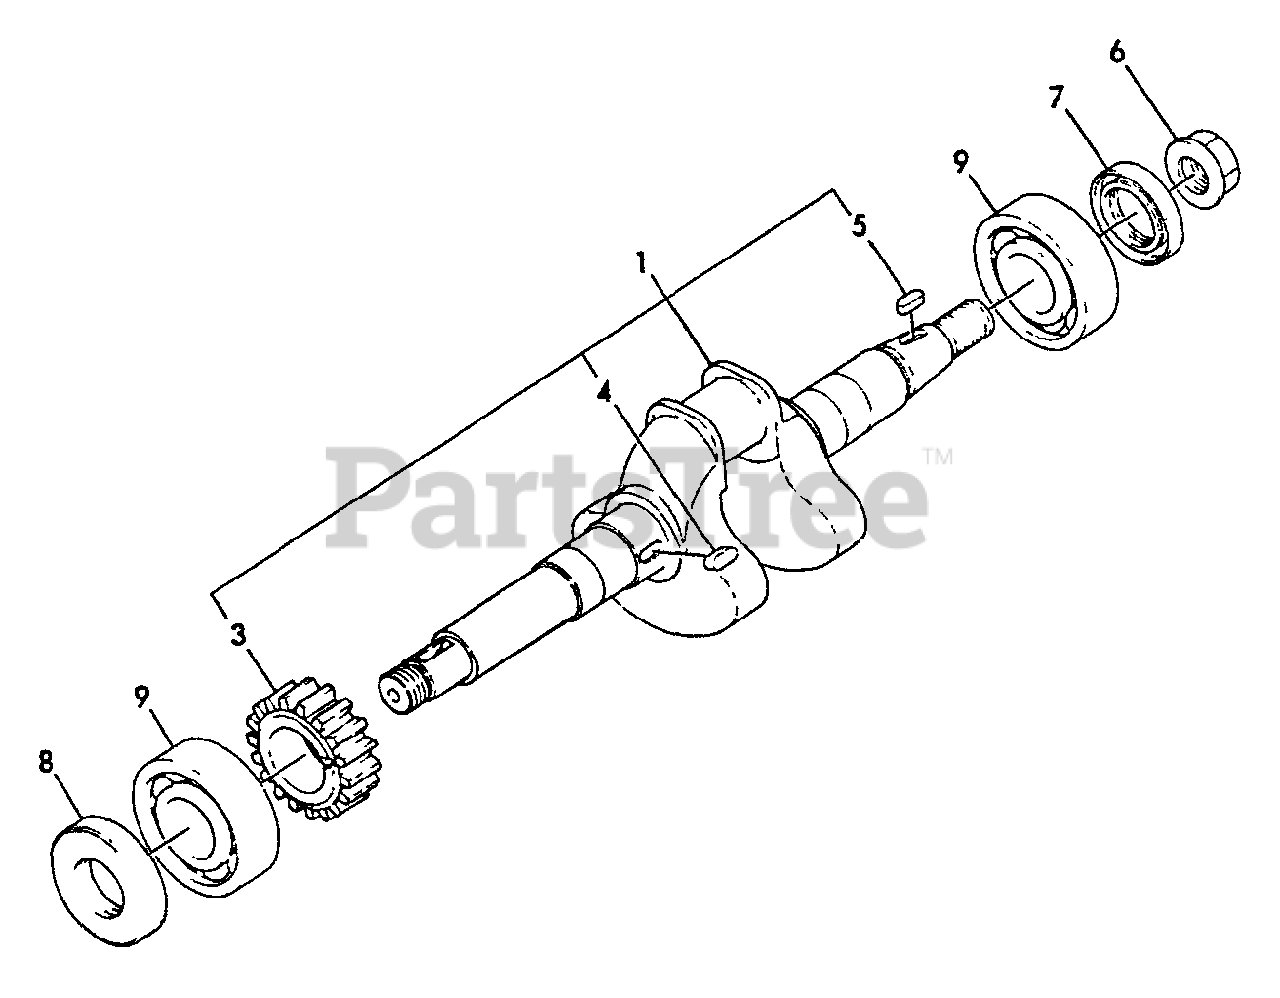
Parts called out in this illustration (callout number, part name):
1	CRANKSHAFT ASSY
3	GEAR, CRANKSHAFT
4	KEY - 4×10
5	KEY - 4×10
6	NUT - 12
7	SEAL, OIL
8	SEAL, OIL
9	BEARING, BALL 6204 C3
